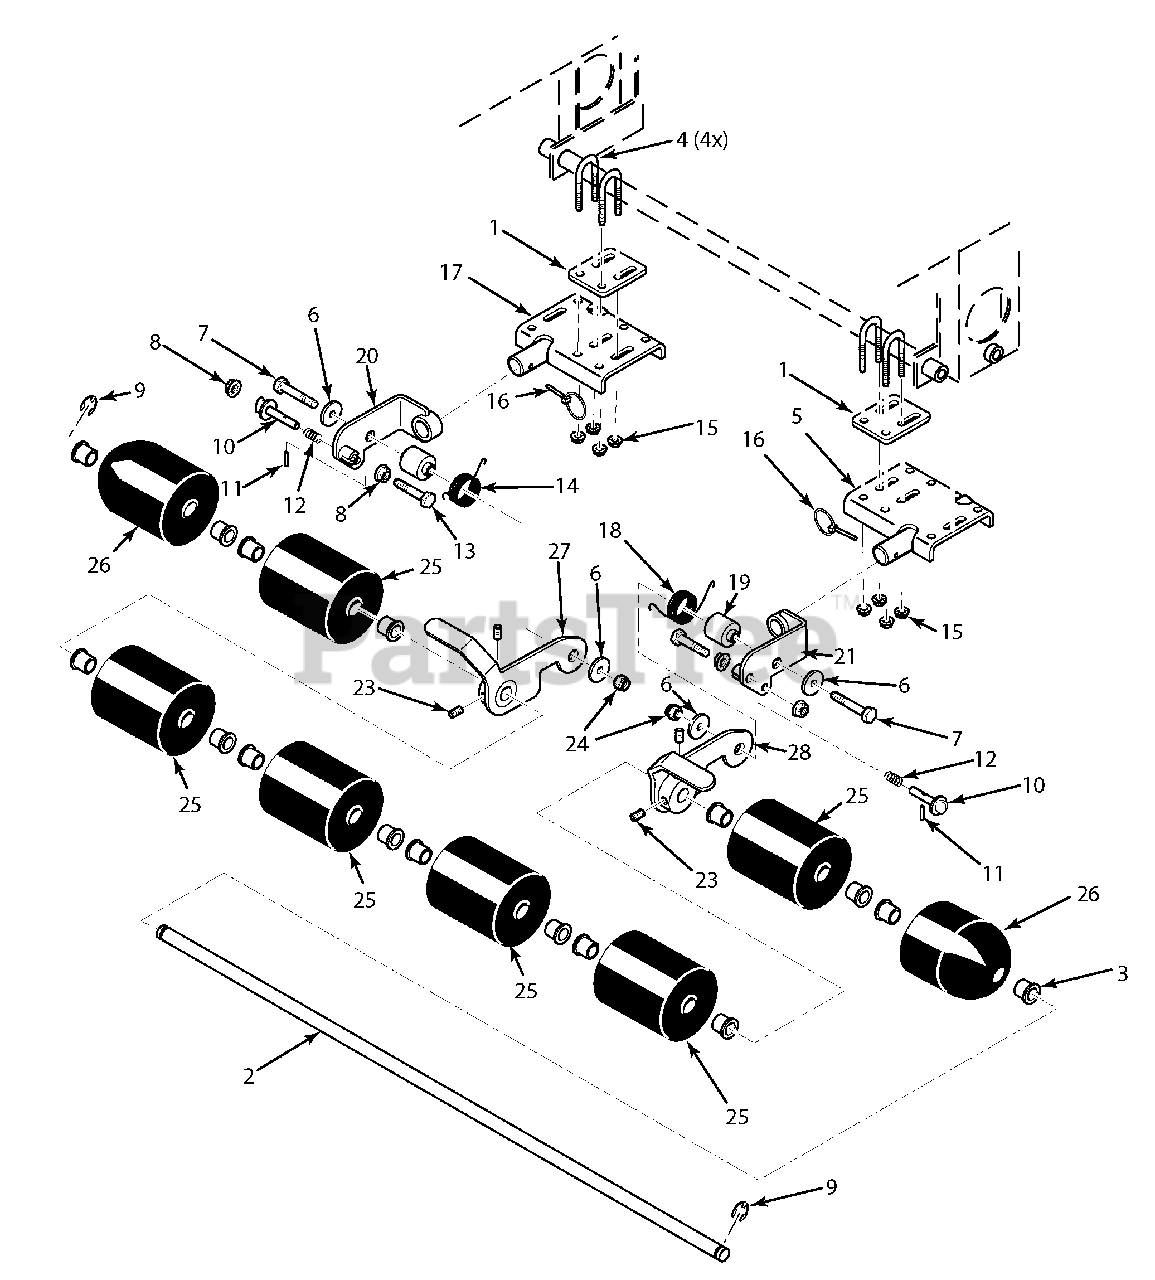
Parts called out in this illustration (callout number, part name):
1	Spacer, Striper Mounting
2	Roller Shaft
3	Bushing, .752 Oilite
4	U-Bolt, 5/16-18 x 1"
5	Mounting Bracket Weldment, LH.
6	Flatwasher, 3/8-.406 x 1-1/2" 7 Gauge
7	Bolt, Hex Head 3/8-16 x 2-3/4"
8	Nut, Serrated Flange 3/8-16
9	Retaining Ring, .750 External "E"
10	Pin, Lift Latch
11	Pin, Slotted Spring .156 x 3/4"
12	Spring, Lock Pin
13	Bolt, Hex Head 3/8-16 x 2-1/2"
14	Spring, Torsion L.H.
15	Nut, Serrated Flange 5/16-18
16	Quick Pin, .188 Dia.
17	Mounting Bracket Weldment, R.H.
18	Spring, Torsion R.H.
19	Hub, Striper
20	Pivot Weldment, L.H.
21	Pivot Weldment, R.H.
22	Hinge Weldment, R.H.
23	Set Screw, 3/8-16 x 1/2"
24	Nut, Elastic Stop 3/8-16
25	Roller Assembly
26	Roller Assembly, Striper End
27	Hinge Weldment, L.H.
